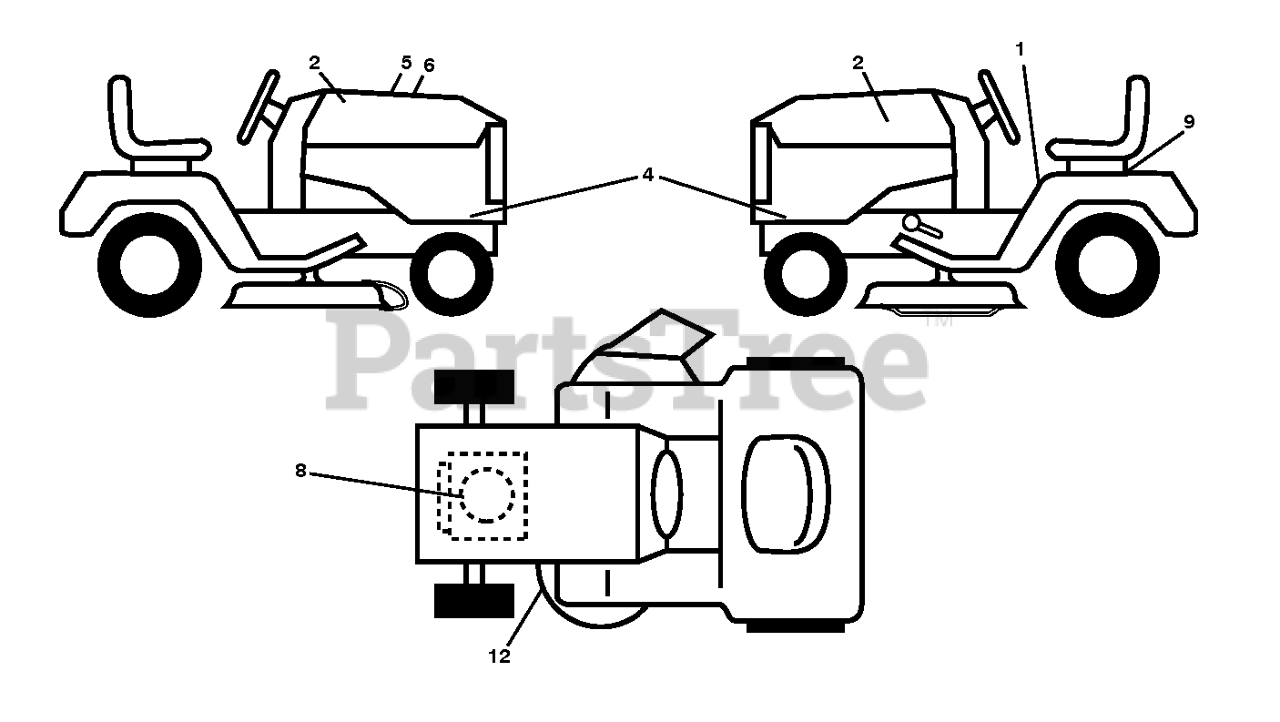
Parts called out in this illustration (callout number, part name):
1	DECAL.FENDER.WARNING
2	DECAL.BADGE.170MM.TEXTLOGO.
4	RP DECAL.SDPNL.HUSGT2.YTH2042.
5	DECAL.WARNING.CUST.RESP.E85.
6	DECAL RPL.BSM33.INT.TLW.42.K46
8	DECAL.ENG.BS.20HPXRD.SL.278416
9	DECAL BTRY SYMBOLS
12	DECAL V BELT SCHEMATIC
